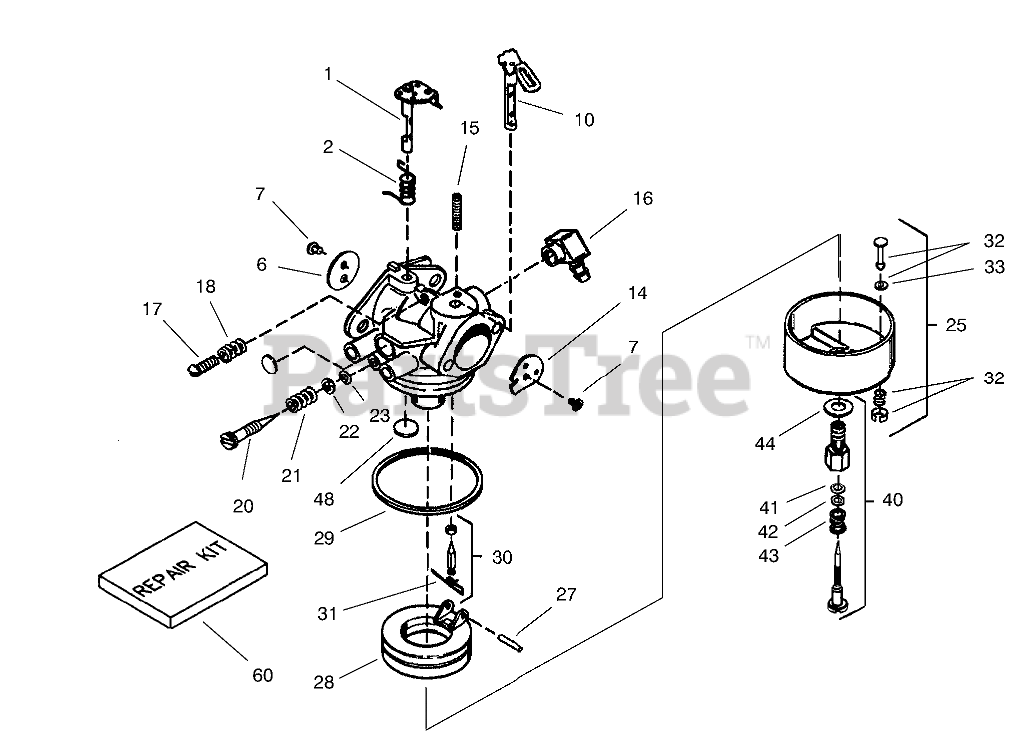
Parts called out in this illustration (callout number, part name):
1	Throttle-Shaft & Lever Asm
2	Spring-Return, Throttle
6	Shutter-Throttle
7	Screw-Shutter
10	Choke Shaft & Lever ASM
14	Choke Shutter
15	Spring-Positioning, Choke
16	Fitting-Fuel
17	Screw-Throttle Crack Screw / Idle Speed
18	Spring-Tension
20	Screw-Idle Mix
21	Spring-Tension
23	"O"Ring
25	Float Bowl Asm.
27	Shaft-Float
28	Float
29	O Ring-Bowl, Float
30	Inlet Needle, Seat and Clip ASM
31	Clip-Spring
32	Bowl Drain ASM
33	Gasket-Plunger, Drain
40	Mian Adj. Screw Asm.
41	"O"Ring
44	Washer-Bowl Nut
47	Plug-Welch, Idle Mixture Well
48	Plug-Welch, Atmospheric Vent
60	Kit-Repair
